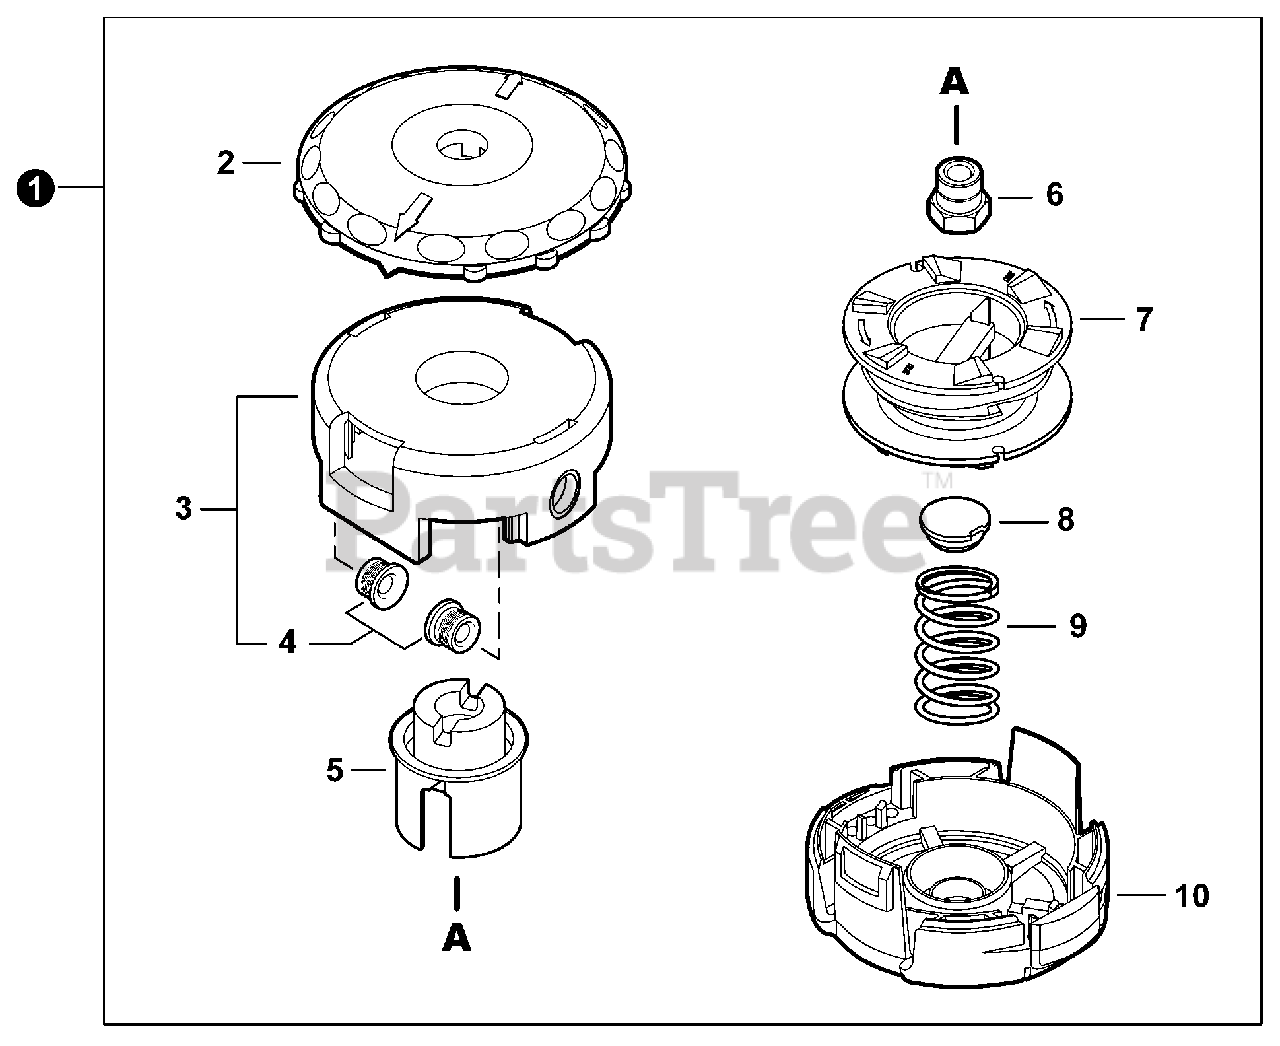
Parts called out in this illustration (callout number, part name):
1	TRIMMER HEAD, SPEED-FEED 400
3	HOUSING ASSY, SPOOL
5	HUB (LH) BLACK
6	BUSHING M10×1.25 LH GOLD
8	CAP, SPRING
9	SPRING, GOLD
10	COVER, SPOOL
